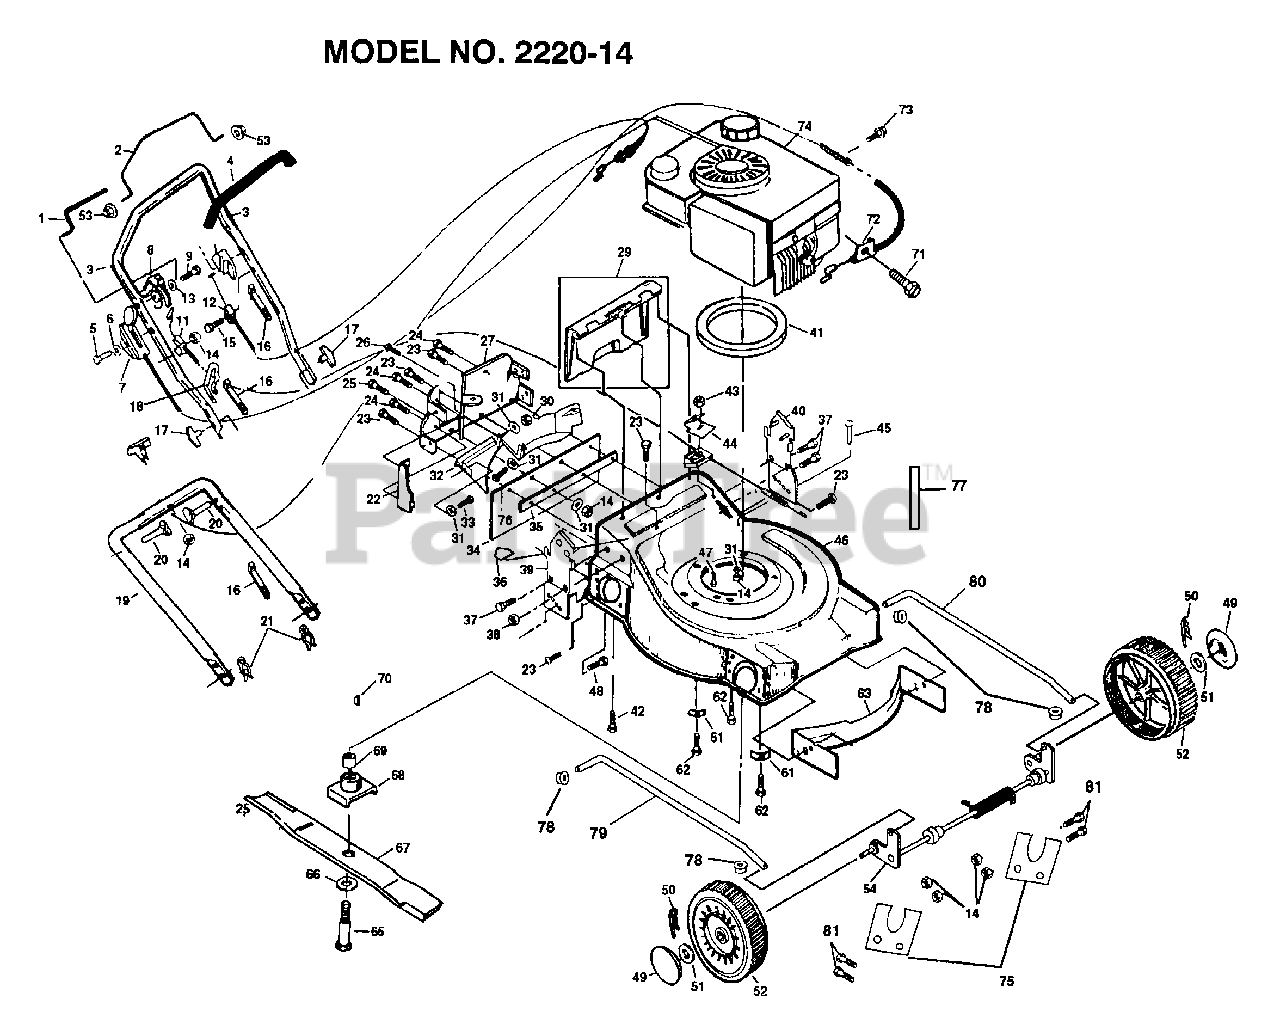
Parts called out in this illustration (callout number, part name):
1	DR BAIL ASSY
2	ENGINE CNTRL BAR
6	WASHER PM
8	DR CONT ACTUATOR
9	SCREW SELF TAP
10	ZONE CONT ACTUATO
21	HAIRPIN COTTER
23	SCREW
24	SCREW SELF TAP
25	HEX SCREW
26	"SCREW,HEX HEAD"
31	WASHER PM
33	SCREW
35	BACKING STRIP
36	DECAL HYT
37	SCREW
39	HNDL BRKT ASSY RIGHT GREEN
40	HNDL BRKT ASSY LEFT GREEN
41	ENGINE SPACER
46	LAWN MOWER HOUSING
47	SCREW PM
49	HUB CAP
50	RETAINER CLIP PM
51	WASHER
52	WHEEL&TIRE ASSY
53	PALNUT
54	FRONT AXLE ASSY
62	SCREW
66	LOCKWASHER
67	"BLADE 22"" PM"
68	"ADAPTOR,BLADE"
70	HI PRO KEY PM
72	CABLE CLAMP
73	SCREW PM
75	RETAINER PLATE
76	HEX THD ROLL SCR
77	"SEAL,REAR DOOR"
78	PUSH ON SPEED NUT
